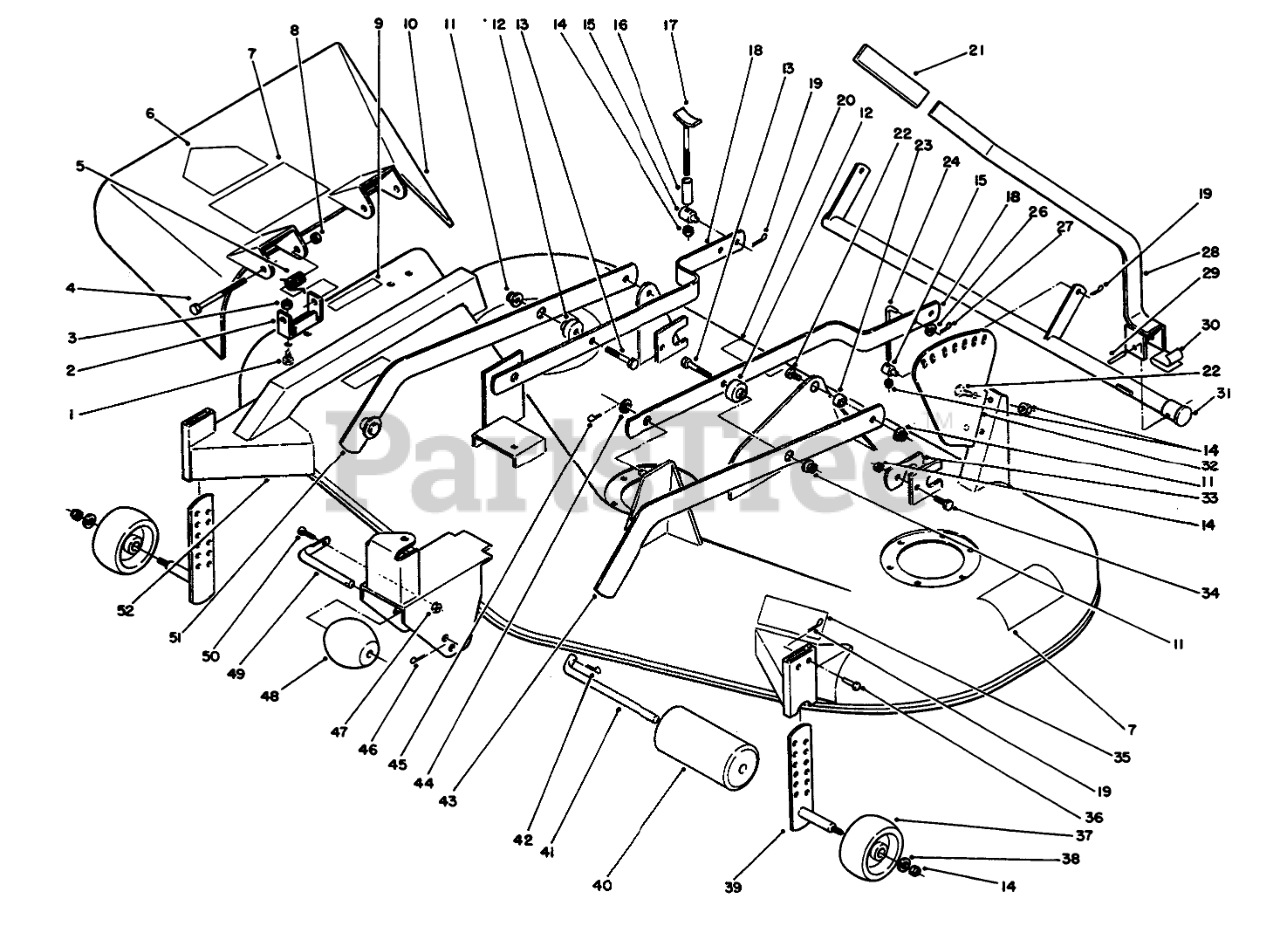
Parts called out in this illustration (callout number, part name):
1	SCREW-CARR
2	Bracket-Pivot
3	NUT-LOCK, NI
4	SCREW-HH
5	SPRING
6	DECAL-DANGER
7	DECAL-DANGER, THROWN OBJECT
8	NUT-HEX
9	DECAL-DANGER
10	Deflector Assembly (Incl. Ref. #6 & 7)
11	LOCKNUT-FLANGE
12	SPACER
13	SCREW-HH
14	NUT-LOCK, NI
15	TRUNNION
16	SPACER .375 ID X 1.6
17	WLDMT-HANGER ROD
18	Bar-Leveler
19	Hairpin Cotter
20	DECAL-BELT ROUTING
22	BOLT-CARR
23	SPACER
24	ROD-LIFT
26	WASHER-PLAIN
27	PIN-COTTER
28	Lever
29	SPIROL PIN
30	CLIP-SPRING
31	Lit Arm Assembly
32	Quadrant
33	LOCK-SHAFT
34	SCREW-HH
35	DECAL - WHEEL ADJUSTMENT
36	PIN-CLEVIS
37	WHEEL-GAGE
38	WASHER-FLAT
39	GAGE-WHEEL
40	ROLLER-DECK
41	SHAFT-ROLLER, REAR
42	PIN-COTTER
43	Draft Bar LH
44	WASHER-FLAT
45	PIN-COTTER
46	PIN-COTTER
47	NUT-LOCK, NI
48	ROLLER
49	SHAFT-ROLLER
50	SCREW-HH
51	Draft Bar RH
52	Deck Assembly
